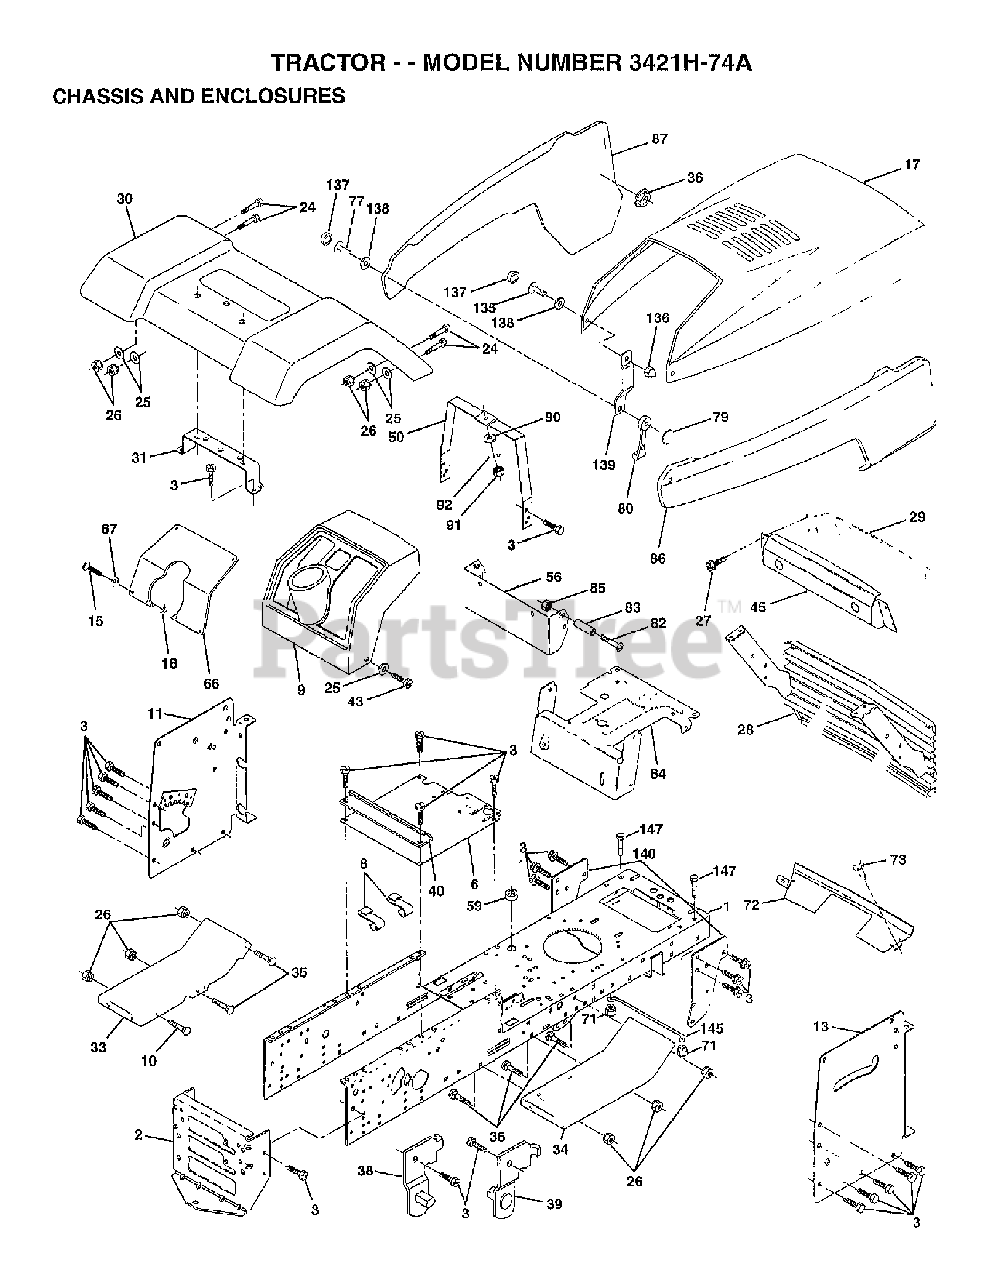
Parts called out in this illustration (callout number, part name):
6	SADDLE FLAT
8	CLIP,INSULATOR
11	PANEL DASH LT
17	Poulan TBD
25	WASHER
26	NUT
30	Poulan TBD
31	BRACKET.SUPPORT.FENDER
33	Poulan TBD
34	Poulan TBD
36	PAL NUT LT
38	BRACKET LH PIVOT
39	BRACKET RH PIVOT
43	SCREW GTV
50	DASH SUPT YP
64	DASH LOWER LT
66	Poulan TBD
67	WASHER
71	NUT.CROWNLOCK.1/4
72	Poulan TBD
73	SCREW CRT
77	SCREW
79	NUT.WELD
80	LATCH.HOOD.
82	SCREW
83	SPACER LT
85	NUT **
86	Poulan TBD
87	Poulan TBD
90	WASHER PM
91	NUT
92	LOCKWASHER
135	SCREW 10-24X3/8
136	NUT
137	SNAP CAP LT
138	WASHER LT
139	BRACKET.SUPPORT.HOOD/PANEL.NLA
140	BRACKET SUSPENSION FRONT
147	BOLT.HEX.1/4.X.3/4.DICHROMATE
